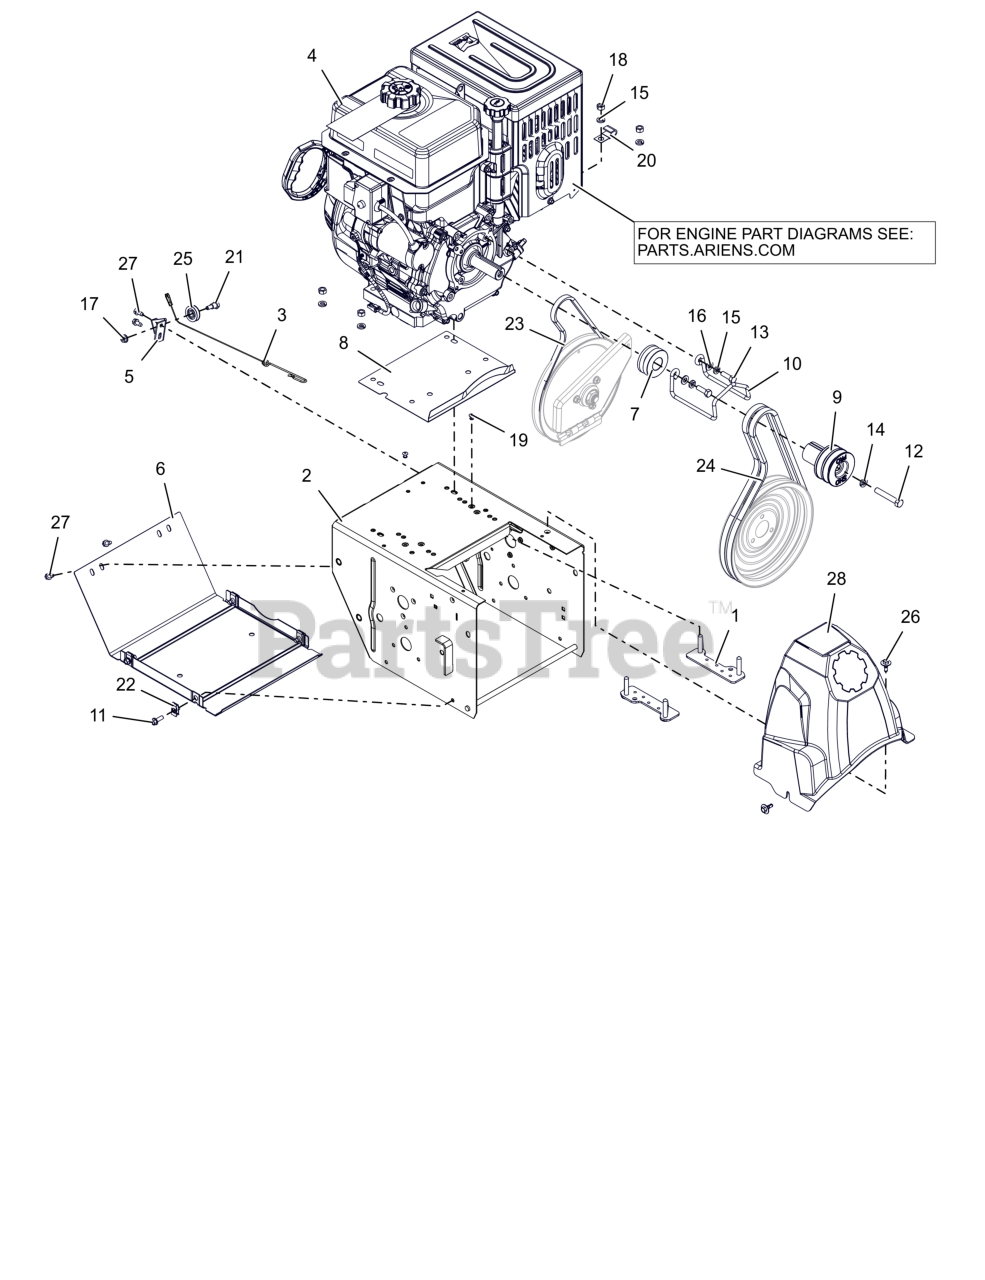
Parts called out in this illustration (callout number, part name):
1	STRAP, BOLT-LARGE
2	FRAME, MAIN - 14GA DELUXE (ORANGE)
3	CABLE, LOWER TRACTION,SS & PRO
4	ENGINE, ARIENS AX420 120V/60W
5	BRKT, CABLE PULLEY
6	COVER, BOTTOM
7	SHEAVE, TRACTION (KEYLESS)
8	BAFFLE, WATER - LARGE BLOCK (ORANGE)
9	SHEAVE,ATTACHMENT-SHO 2 GRV
10	FINGER, BELT
11	BLT, HWH .25-20X.75 G5 ZCC
12	BLT, HEX .38-24X2.25 G5 ZCC
13	BLT, HEX 0.3125-24X1 G5 ZCC
14	WSHR,LK-REG .375X.094 ZCC
15	WSHR, LK-HVY .312X.097 ZCC
16	WSHR,FLT .344X.688X.065 ZCC
17	NUT-LK-TOP-FLG .250-20 GF ZCC
18	NUT, HEX .312-18 ZCC
19	RVT, POP .1875 ZCC
20	J-CLAMP
21	BOLT, SHLDR -.375 X .375 X .25-20
22	NUT-RTNR .25-20X.56
23	V-BELT, 3L-WRAPPED
24	V-BELT, HA-RAW EDGE (SET)
25	PULLEY, CABLE
26	SCR-TAP .25-20X.5 CAPTIVE
27	SCR-TAP .25-20X.50 HWH ZCC
28	COVER, BELT
